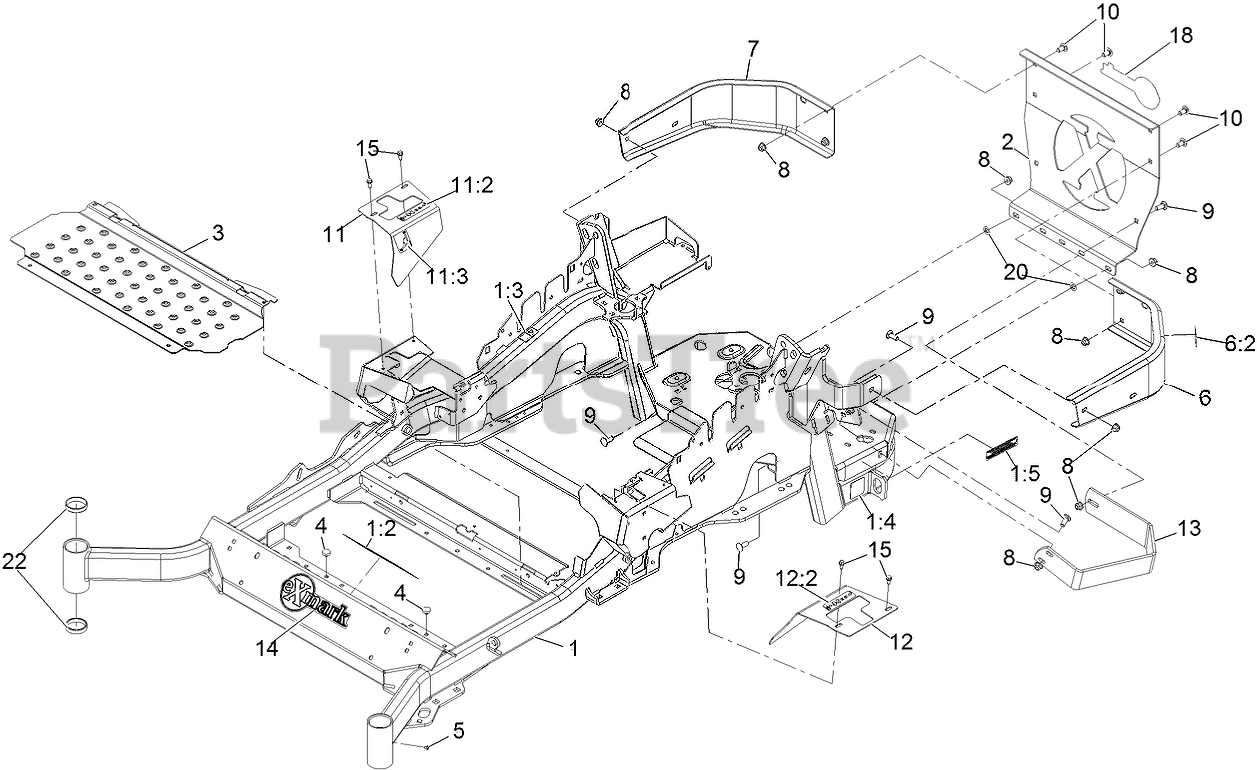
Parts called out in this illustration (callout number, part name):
1	MAINFRAME ASM
1:2	DECAL-DANGER
1:3	DECAL-WARNING
1:4	DECAL-HAZARD, PINCHED FINGER
1:5	DECAL-ARRESTOR, SPARK
2	PLATE,REAR GUARD
6	LH BUMPER ASM
6:2	DECAL-WARNING
7	BUMPER-RH
8	NUT-HF, NI
9	SCREW-CARR
10	SCREW-CARR
11	RH MOTION CONTROL COVER ASM
11:2	DECAL-CONTROL, MOTION
11:3	DECAL-PARK BRAKE, CE
12	LH MOTION CONTROL COVER ASM
12:2	DECAL-CONTROL, MOTION
13	GUARD-MUFFLER
14	DECAL-EXMARK
15	SCREW-HWH
18	DECAL, EXMARK LOGO
20	NUT-PUSH
22	CUP-BEARING
